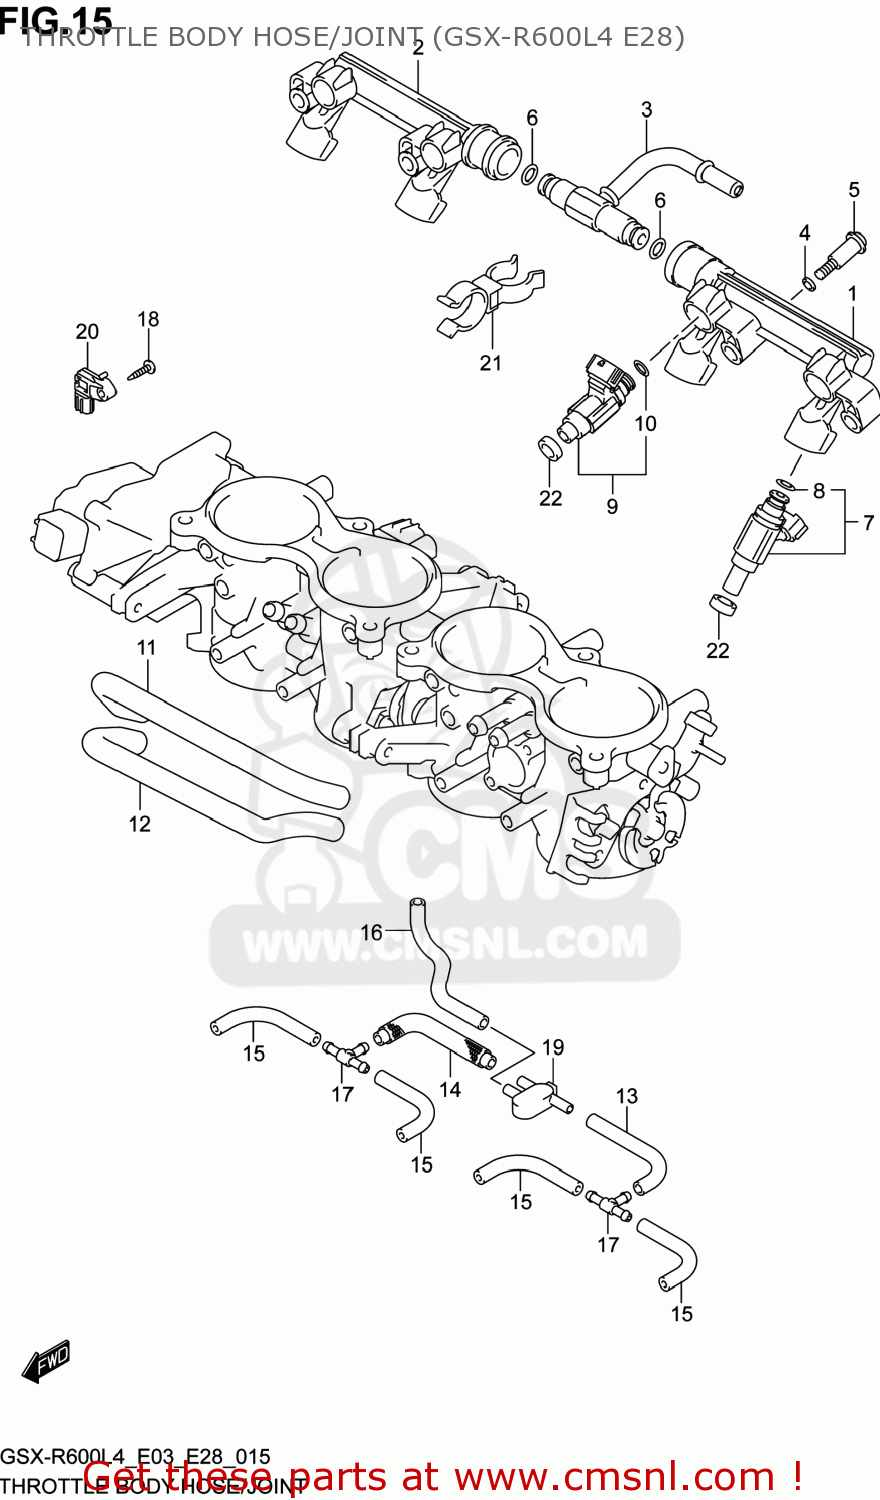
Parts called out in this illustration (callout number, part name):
1	DELIVERY PIPE
2	DELIVERY PIPE
3	NIPPLE ASSY
4	PACKING (NAS)
5	SCREW
6	O RING
7	INJECTOR ASSY
8	O-RING
9	INJECTOR ASSY
10	O-RING
11	HOSE
12	HOSE
13	HOSE
14	HOSE
15	HOSE(L:425)
16	HOSE
17	3WAY,VACUUM HOSE
18	SCREW
19	JOINT
20	SENSOR,BOOST
21	CLAMP
22	SEAL
